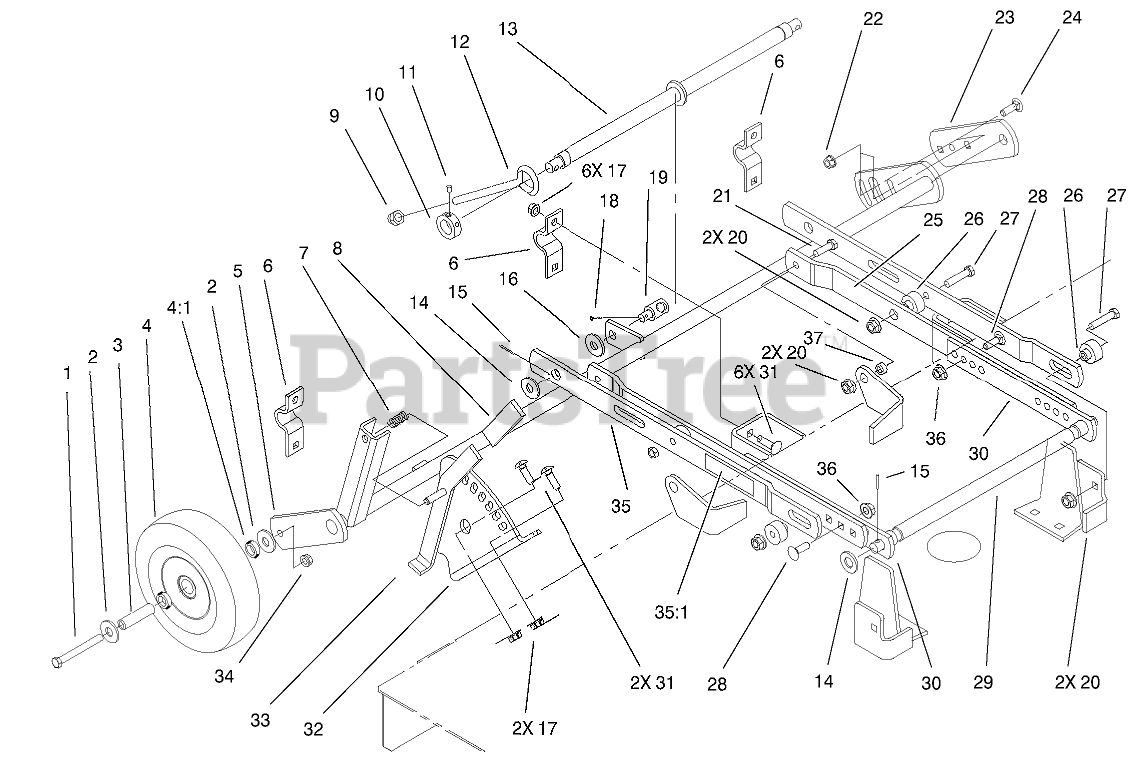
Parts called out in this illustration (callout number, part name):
1	SCREW-HH
2	WASHER-FLAT
3	SPACER
4	ASSY-GAUGE WHEEL
4:1	Bearing-Ball
5	WHEEL SUPPORT
6	Clamp
7	SPRING-COMPRESSION
9	NUT-LOCK, NI
10	COLLAR
11	SCREW-SET, HSH
12	ROD-ADJUSTMENT, LEVEL
13	SHAFT-LEVELER
14	WASHER-FLAT
15	PIN-ROLL, SPIROL
16	WASHER-FLAT
17	NUT-LOCK, NI
18	PIN-COTTER
19	TRUNNION
20	LOCKNUT-FLANGE
21	SCREW-HH
22	NUT-FLANGE
23	SUPPORT-GAGE WHEEL
24	BOLT-CARR
25	DRAFTBAR
26	SPACER
27	SCREW-HH
28	SCREW-CARR
29	Shaft-Draftbar
30	DRAFTBAR-ADJUSTMENT
31	BOLT-CARR
32	QUADRANT-DECK
33	HOC Lever
34	NUT-HEX
35	LH LEVELER ASM
35	RH LEVELER ASM
35:1	DECAL-WARNING
36	NUT-LOCK, CONE
37	SPACER
